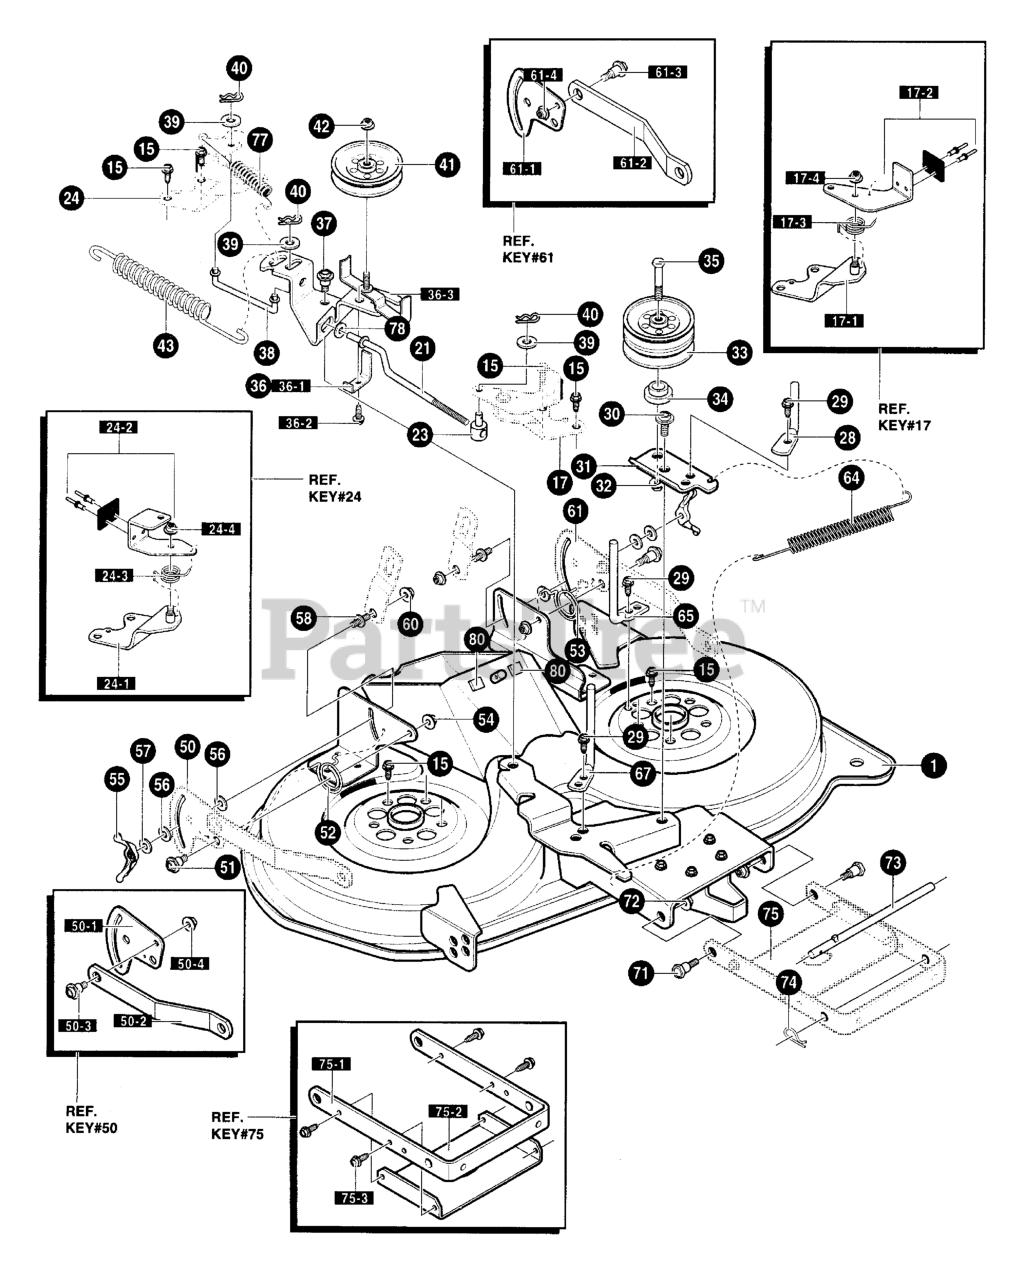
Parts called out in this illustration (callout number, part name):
1	HOUSING, 40" DECK
17	BRAKE ARM ASSEMBLY LH
17-1	BRAKE SUPPORT ASSEMBLY LH
17-2	BRAKE ARM ASSEMBLY LH
17-3	SPRING, TORSION
17-4	NUT, 5/16-18
21	LINK, BRAKE LH
23	NUT, ADJUST
24	BRAKE ARM ASSEMBLY RH
24-1	BRAKE SUPPORT ASSEMBLY RH
24-2	BRAKE ARM ASSEMBLY RH
24-3	SPRING, TORSION
24-4	NUT, 5/16-18
28	GUIDE, BELT
29	SCREW, 5/16-18 x 0.50
30	BOLT, SHOULDER
31	ARM, DOUBLE IDLER
32	NUT, 3/8-16
33	PULLEY,IDLER DOUBLE VEE
35	SCREW, 3/8-16 x 3.00
36	IDLER ARM ASSY
36-1	SPRING - GUIDE BELT
36-2	SCREW, 1/4-20X .50
36-3	IDLER ARM ASSEMBLY
37	BOLT, SHOULDER
38	LINK, BRAKE RH
39	WASHER, FLAT
40	HAIR PIN
41	PULLEY, V IDLER 4"
42	NUT, 3/8-16 HWDFLLK MACK
43	SPRING, EXTENSION
50	ASSEMBLY, PLATE REAR SUS.BRKT. RH
50-1	PLATE - SUSPENSION
50-2	SUSPENSION BRACKET REAR
50-3	BOLT, SHOULDER 3/8-16 (9X52)
50-4	NUT, 3/8-16 HWDFLLK MACK (15X84)
51	BOLT, SHOULDER .375
52	SPRING, TORSION RH
53	SPRING, TORSION LH
54	NUT, 3/8-16 HWDFLLK MACK
55	WINGNUT, 5/16-18
56	PAD, FRICTION
57	WASHER
58	PIN, HANGER
60	NUT, 3/8-16
61	ASSEMBLY, PLATE, REAR SUS.BRKT. LH
61-1	PLATE - SUSPENSION
61-2	SUSPENSION BRACKET REAR
61-3	BOLT, SHOULDER 3/8-16
61-4	NUT, 3/8-16
64	SPRING, EXTENSION
65	GUIDE, BELT
67	GUIDE, BELT
71	BOLT, SHOULDER
72	NUT, 3/8-16
73	ROD, HANGER
74	PIN, HAIR
75	ASSEMBLY, BRACKET & STIFFENER
75-1	BRACKET, FRONT SUSPENSION
75-2	STIFFENER
75-3	SCREW, 5/16-18 x 0.75
77	SPRING, EXTENSION
78	WASHER, FLAT
80	PAD, ADHESIVE
